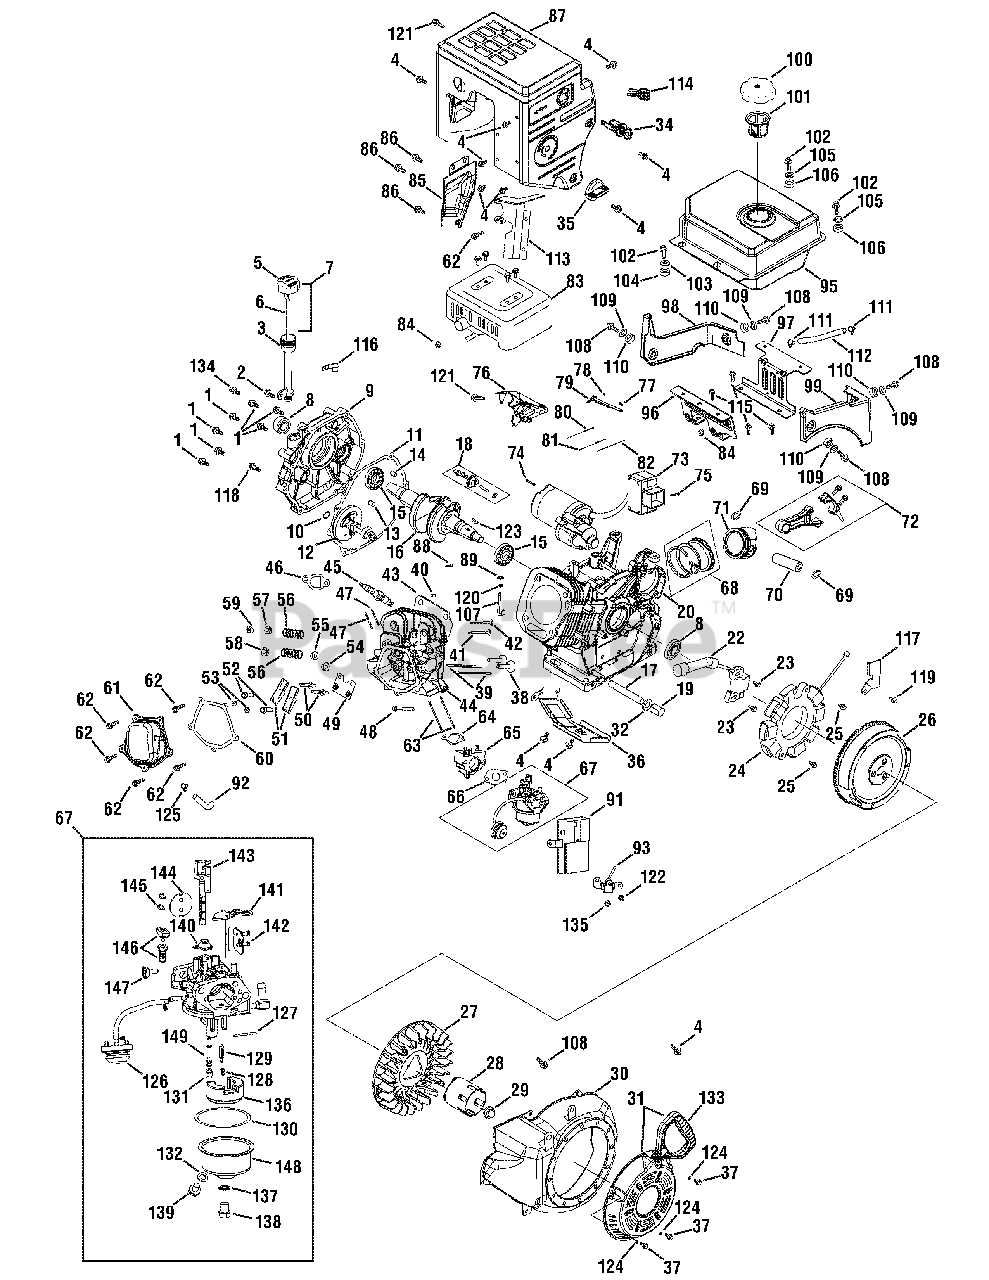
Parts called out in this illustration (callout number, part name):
1	Flange Bolt
2	Flange Bolt
3	Dipstick Tube
4	Flange Bolt
5	Oil Cap
6	Dipstick
7	Dipstick Assembly
8	Crankshaft Oil Seal
9	Crankcase Cover
10	Flat Washer
11	Crankcase Cover Gasket
12	Camshaft Assembly
13	Dowel Pin
14	Dowel Pin
15	Ball Bearing
16	Crankshaft Assembly
17	Oil Drain Bolt
18	Governor Gear Assembly
19	Extended Oil Drain Plug
20	Crankcase
22	Ignition Coil
23	Flange Bolt
24	Stator
25	Flange Bolt
26	Flywheel
27	Cooling Fan
28	Starter Cup
29	Flange Nut
30	Blower Housing
31	Recoil Starter Assembly
32	Oil Drain Washer
34	Ignition Switch
35	Choke Knob
36	Cylinder Baffle
37	Flange Bolt
38	Tappet
39	Push Rod Kit
40	Dowel Pin
41	Intake Valve
42	Exhaust Valve
43	Head Gasket
44	Cylinder Head
45	Spark Plug
46	Muffler Gasket
47	Exhaust Stud
48	Flange Bolt
49	Pushrod Guide Plate
50	Rocker Stud Bolt
51	Rocker Arm
52	Valve Adjusting Nut
53	Pivot Locking Nut
54	Intake Valve Seal
55	Exhaust Valve Spring Support
56	Valve Spring
57	Exhaust Spring Retainer
58	Intake Spring Retainer
59	Exhaust Valve Cap
60	Valve Cover Gasket
61	Valve Cover
63	Carburetor Stud
64	Intake Gasket
65	Carburetor Insulator
66	Carburetor Gasket
67	Carburetor Assembly
68	Piston Ring Set
69	Piston Pin Clip
70	Piston Pin
71	Piston
72	Connecting Rod Assembly
73	Electric Starter
74	Flange Bolt
76	Throttle Control Assembly
78	Nut
79	Governor Arm Bracket
80	Governor Spring
81	Throttle Return Spring
82	Governor Rod
83	Muffler Assembly
85	Muffler Baffle
86	Flange Bolt
87	Muffler Shield
88	Governor Shaft Clip
89	Washer
91	Heater Box
92	Breather Hose
93	Choke Assembly
95	Fuel Tank
96	Fuel Tank Mounting Bracket
97	Fuel Tank Mounting Bracket
98	Fuel Tank Shroud
99	Engine Shroud
100	Fuel Cap Assembly
101	Fuel Filter
102	Flange Bolt
103	Washer
104	Bushing
105	Washer
106	Bushing
107	Governor Shaft
108	Flange Bolt
109	Washer
110	Bushing
111	Fuel Hose Clamp
112	Fuel Hose
113	Carburetor Heat Shield
114	Throttle Knob
115	Flange Bolt
116	Oil Tube Support Bracket
117	Alternator Wire Clamp Bracket
118	Flange Bolt
119	Flange Bolt
120	Governor Shaft Seal
121	Flange Bolt
122	Nut
123	Flywheel Key
124	Flat Washer
125	Breather Hose Clip
126	Primer
127	Float Pin
128	Needle Valve Spring
129	Needle Valve
130	Bowl Gasket
131	Main Jet
132	Fuel Drain Plug Gasket
133	Starter Handle
134	Bolt
135	Lock Washer
136	Carburetor Float
137	Fuel Bowl Gasket
138	Fuel Drain Bolt
139	Fuel Drain Plug
140	Throttle Pressure Plate
141	Choke Shaft
142	Choke Plate
143	Throttle Shaft
144	Throttle Plate
145	Screw
146	Idle Jet Assembly
147	Idle Speed Adjusting Screw
148	Fuel Bowl
149	Main Nozzle
